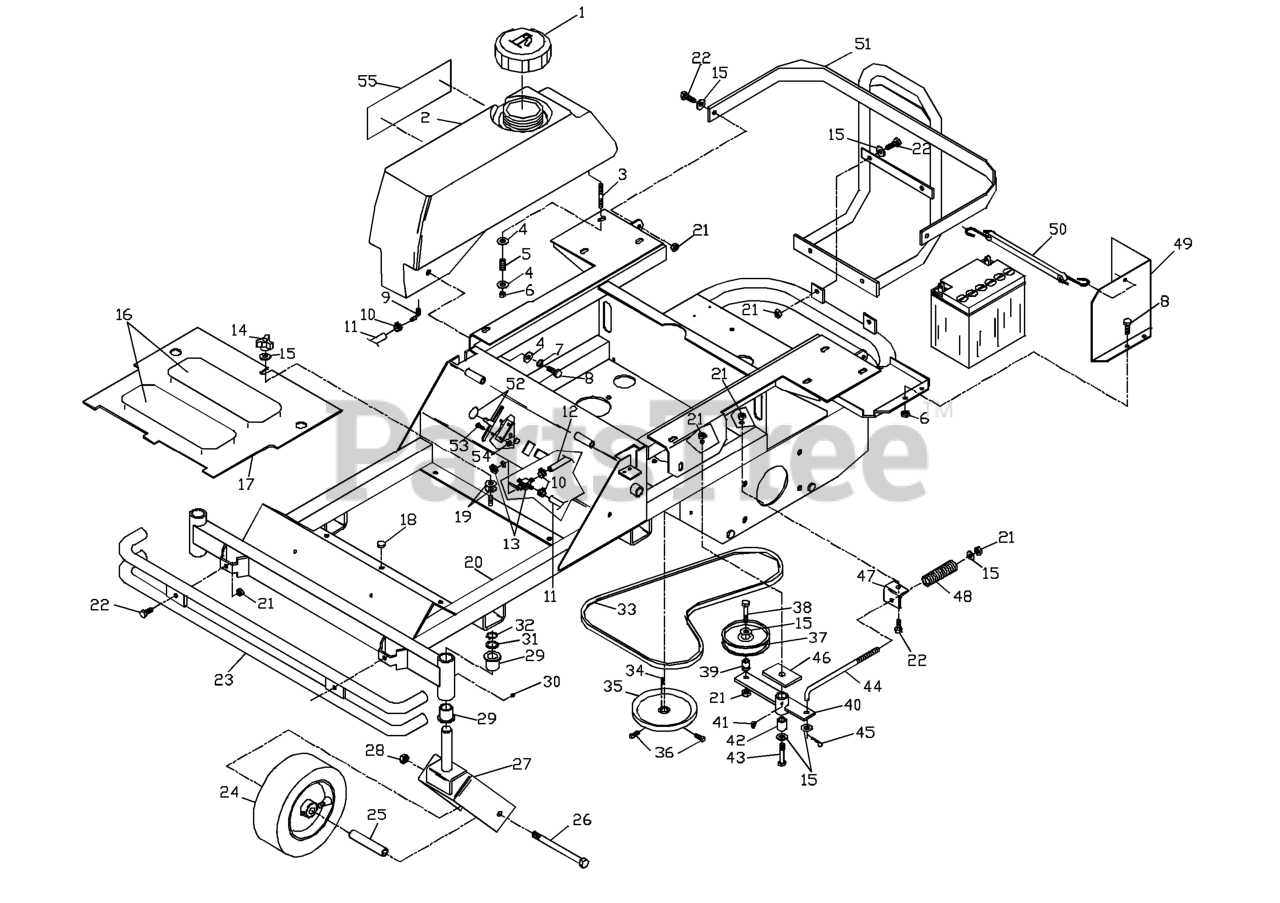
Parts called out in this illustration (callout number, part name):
1	FUEL CAP
2	FUEL TANK RT
3	STUD, 5/16C
4	WASHER 5/16 FLAT
6	NUT 5/16C CENTERLOCK
7	WASHER.LOCK.HVY.HLCL.SPR.5/16
8	HCS 5/16C X 3/4
9	HOSE BARB 90 DEGREE
10	HOSE CLAMP
11	FUEL LINE 21.5" TANK
12	FUEL LINE, ENGINE
13	FUEL VALVE
14	KNOB, THREE PRONG
15	WASHER 3/8 FLAT
16	ANTI-SKID PAD
17	FOOTPLATE
18	GROMMET, BUMPER
19	WASHER, 3/8 DISC SPRING SPEC
20	FRAME W/DECALS KOHLER
20	FRAME W/DECALS KAWASAKI
21	NUT 3/8C CENTERBLOCK
22	HCS 3/8-16X1.GRD.5.ZD
23	BUMPER, FRONT
24	TIRE, CASTER (COMPLETE)
24	TIRE.11X4.00-5NHS.4PR.SMOOTH
24	ROLLER BEARING 1"
24	ZERK
24	BEARING RETAINER
24	ROLLER BEARING 2 1/4"
26	HCS 1/2C X 5 1/2
27	YOKE WELDMENT ORANGE
28	NUT 1/2-13 HEX NYLOC ZD
29	BUSHING, FLANGED
30	ZERK
31	BSHG .875 X 1.375 X .074 ZD
32	RETAINING RING, 7/8"
34	KEY 5 MM SQ X 25 MM
36	SCREW 5/16C X 5/8 SQ HEAD
37	IDLER PULLEY
38	HCS 3/8-16 X 1 3/4 GR5
39	BUSHING, IDLER FLANGE
40	IDLER ARM WELDMENT
41	ZERK
42	PIVOT BUSHING
43	HCS 3/8C X 3
44	TENSION ROD
45	COTTER PIN 3/32 X 3/4
46	SUPPORT PLATE
47	TENSION BRACKET
48	COMPRESSION SPRING
49	BATTERY GUARD W/DECA
50	BATTERY STRAP
51	ENGINE GUARD W/DECAL
52	THROTTLE CABLE
53	HCS #10-24 X 1/2
54	NUT 10-24 NYLOC
55	DECAL, ZTH4818
55	DECAL ZTH4820
55	DECAL, ZTH4821
56	HCS 3/8C X 2 1/4
57	WEIGHT BLOCK
58	CHOKE CONTROL, COMPLETE
